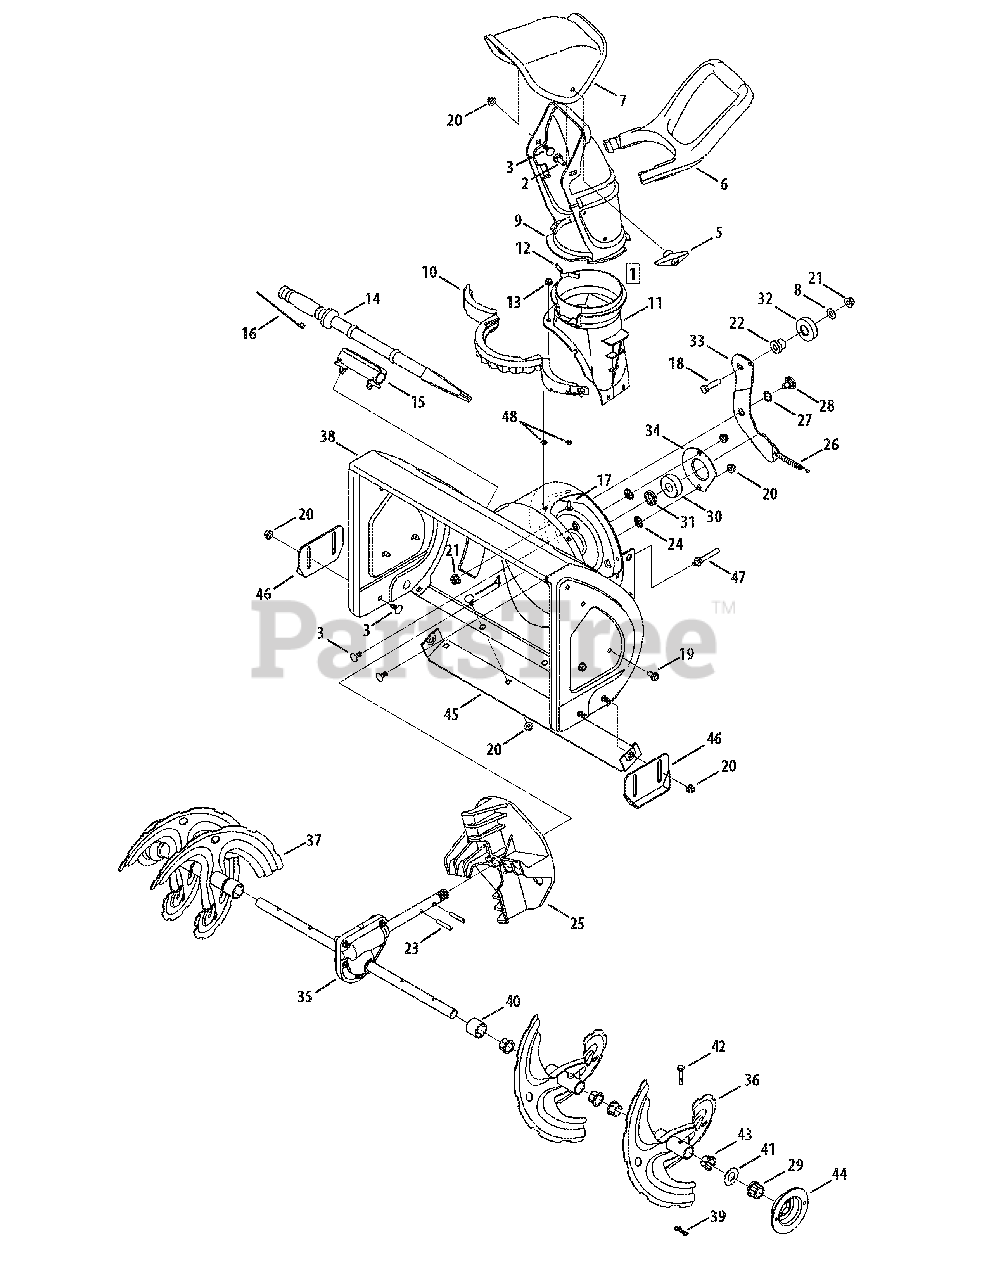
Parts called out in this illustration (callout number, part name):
1	Chute Assembly
2	Carriage Bolt 5/16-18 x 1.0"
3	Carriage Bolt 5/16-18
4	Carriage Bolt 5/16-18 x .62
5	Wing Knob 5/16-18 Black
5	Wing Knob 5/16-18 Yellow
6	Chute Handle
7	Upper Chute
8	Flat Washer .385 x .87 x .06
9	Lower Chute
10	Chute Ring
11	Chute Adapter 5" Dia.
12	Chute Adjustment Spring
13	Flange Lock Nut 1/4-20
14	Clean-out Tool
15	Clean-out Tool Mount
16	Cable Tie
17	Carriage Screw 1/4-20 x 0.62"
18	Hex Bolt 3/8-16 x 1.50"
19	AB Screw 5/16-18 x .750
20	Flange Lock Nut, 5/16-18
21	Flange Lock Nut, 3/8-16
22	Shoulder Spacer
23	Spiral Pin
24	Push On Nut
25	Impeller
26	Extension Spring
27	Wave Washer
28	Shoulder Screw 3/8-16
29	Hex Flange Bearing
30	Ball Bearing
31	Spacer
32	Flat Idler
33	Auger Idler Bracket
34	Bearing Housing
35	Auger Gearbox Assembly
36	Auger Assembly - LH - Black
36	Auger Assembly - LH - Red
37	Auger Assembly - RH - Black
37	Auger Assembly - RH - Red
38	Auger Housing, 22" - Red
38	Auger Housing, 22" - Green
38	Auger Housing, 22" - Black
39	Bow Tie Cotter Pin 72
40	Spacer, 1.25 x.75 x 1.00
41	Flat Washer
42	Shear Pin,.25 x 1.50
43	Flange Bushing
44	Hex Bearing Housing
45	Shave Plate 2.25 x 21.66 LG - Red
45	Shave Plate 2.25 x 21.66 LG - Green
45	Shave Plate 2.25 x 21.66 LG - Black
46	Skid Shoe
47	Belt Keeper
48	Push Nut
